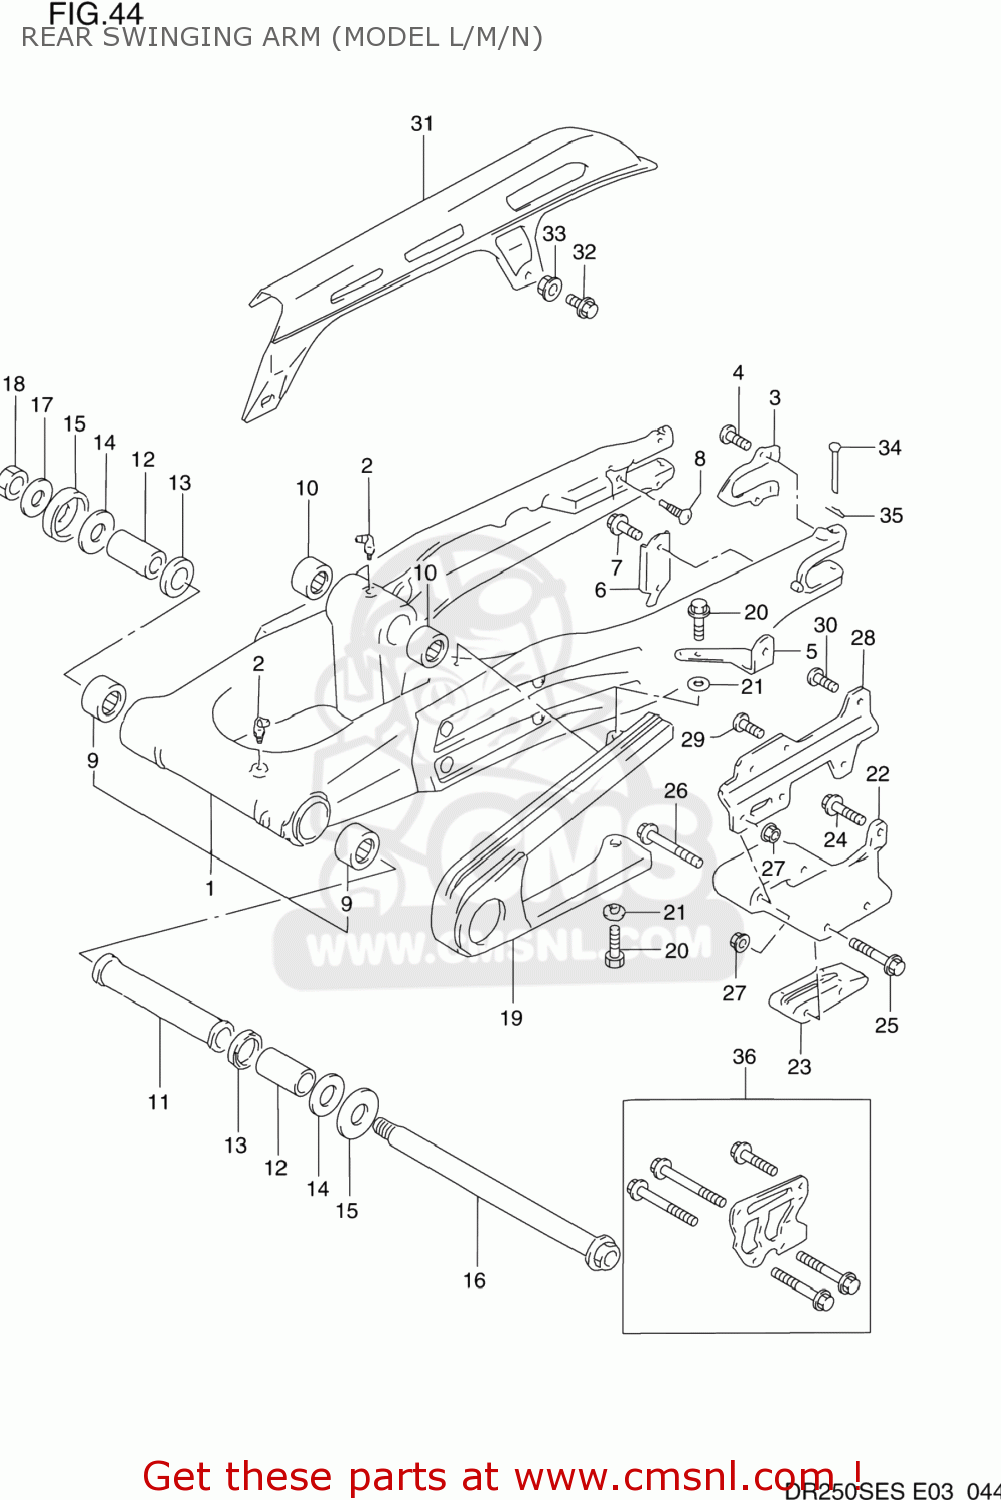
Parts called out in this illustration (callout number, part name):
1	SWING ARM ASSEMBLY,REAR
2	NIPPLE,GREASE
3	PLATE,SWING ARM RR
4	SCREW (5X8)
5	PLATE,CHAIN CASE FTG FR
6	PLATE,CHAIN CASE FTG RR
7	BOLT
8	SCREW (M10X21)
9	BEARING(22X29X30)
10	BEARING(20X27X23.5)
11	SPACER,SWING ARM PIVOT,CENTER
12	SPACER,SWGARM PIVOT BRG
13	SEAL,OIL(22X29X4)
14	WASHER
15	COVER,SWINGINGARM PIVOT
16	SHAFT,SWINGING ARM PIVOT
17	WASHER
18	NUT
19	BUFFER,CHAIN TOUCH DEFENSE
20	BOLT
21	WASHER
22	GUIDE,CHAIN
23	DEFENSE,CHAIN GUIDE
24	BOLT 6X25
25	BOLT,UNDER
26	BOLT
27	NUT
28	BRACKET,CHAIN GUIDE
29	SCREW
30	SCREW(6X12)
31	CASE,CHAIN
32	BOLT
33	WASHER
34	PIN
35	CLIP
36	PLATE SET,CHAIN GUIDE
